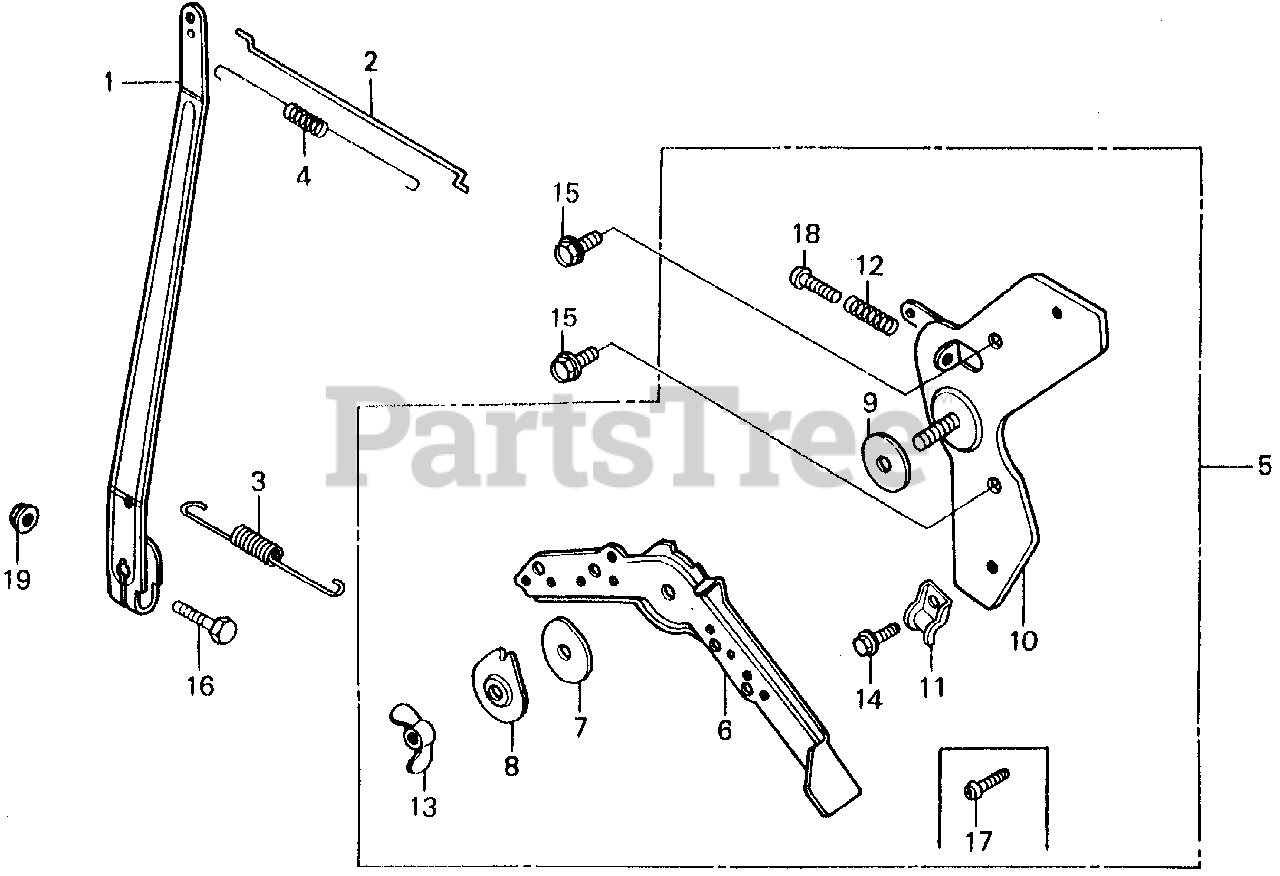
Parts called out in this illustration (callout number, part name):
1	ARM, GOVERNOR
2	ROD, GOVERNOR
3	SPRING, GOVERNOR
4	SPRING, THROTTLE RETURN
5	CONTROL ASSY.
6	LEVER, CONTROL
7	SPRING, LEVER
8	WASHER, CONTROL LEVER
9	SPACER, CONTROL LEVER
10	BASE, CONTROL LEVER
11	HOLDER, CONTROL CABLE
12	SPRING, CONTROL ADJUSTING
13	WINGNUT (6MM)
14	BOLT, FLANGE (5X10)
15	BOLT, FLANGE (6X12) (CT200)
16	BOLT, HEX. (6X20)
17	SCREW, PAN (5X10)
18	SCREW, PAN (5X22)
19	NUT, FLANGE (6MM)
